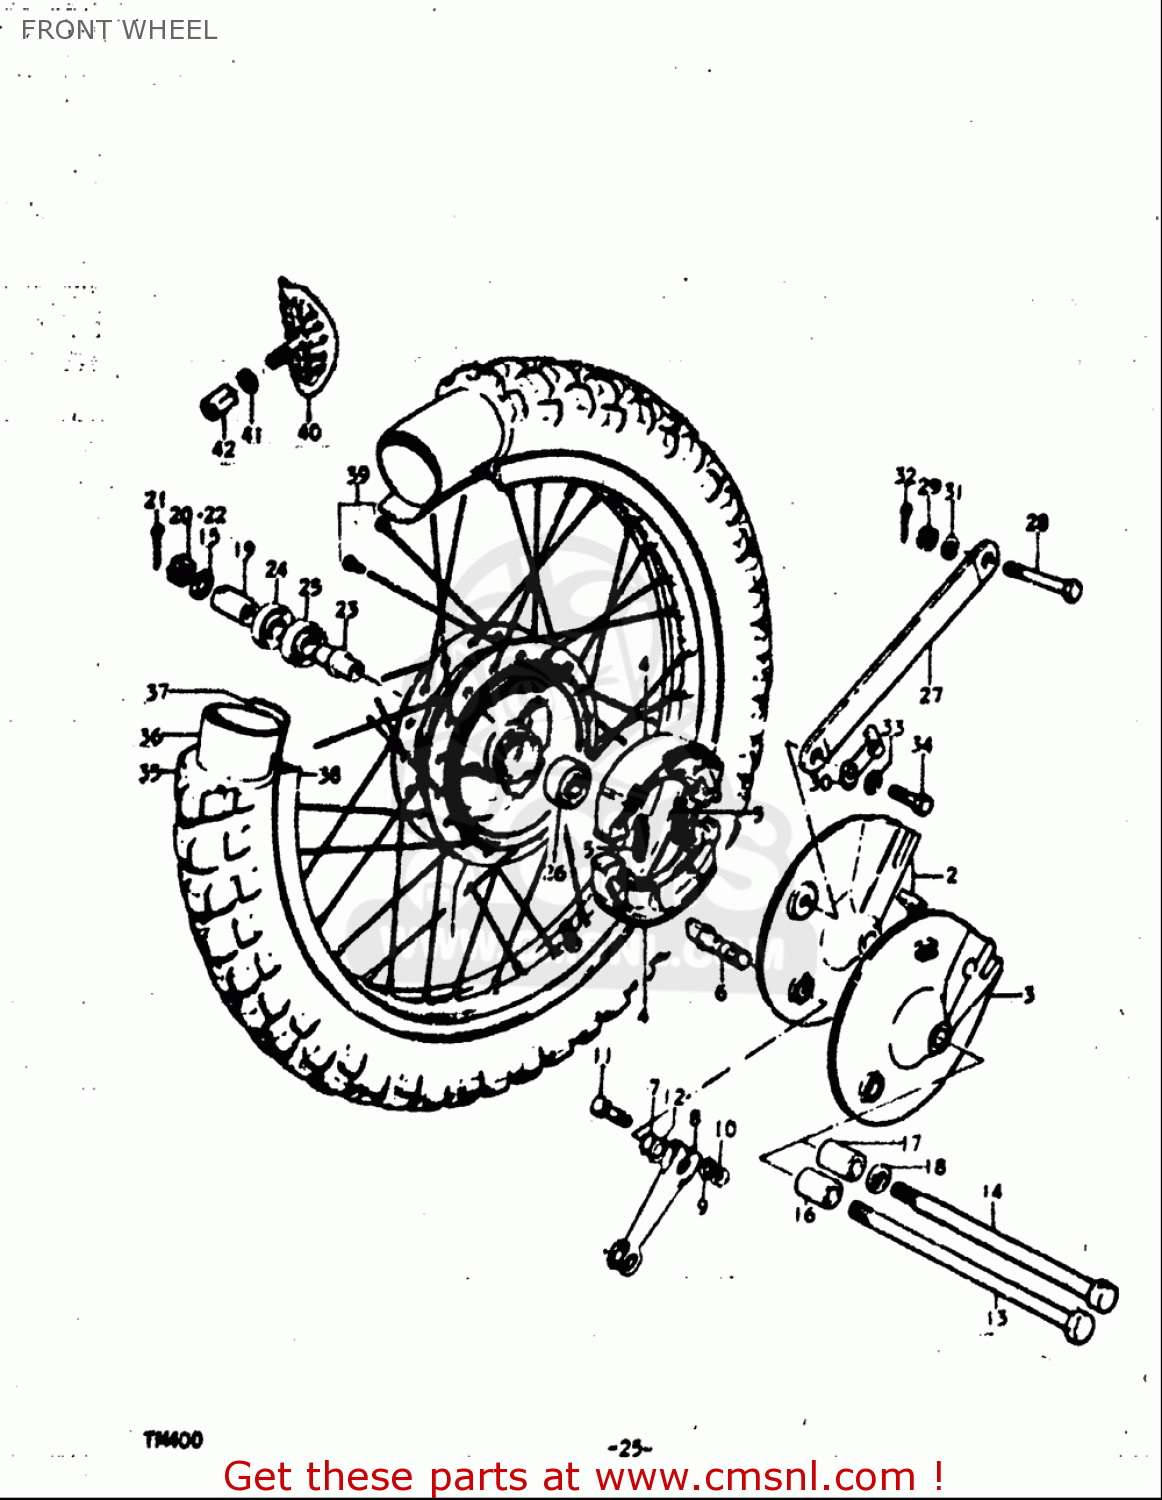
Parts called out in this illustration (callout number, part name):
5	SPRING(L:35.8)
6	CAM,FR BRAKE
7	O RING(D:2.5,ID:11.4)
9	WASHER
10	NUT
11	BOLT(6X31)
12	WASHER(12.5X20X1)
13	AXLE,FR
14	AXLE,FR
15	WASHER
16	NUT,FRONT AXLE
17	SPACER(12X20X34.5)
20	NUT (12MM)
21	PIN
22	NUT 12MM
24	OIL SEAL(17X38X5)
25	BEARING
26	BEARING
27	LINK, FRONT TORQUE
29	NUT
30	MUD FLAP,FRONT FENDER,LEFT
31	WASHER
33	WASHER,LOCK
34	BOLT
36	TUBE
40	STOPPER,BEAD(1.85)
41	WASHER
